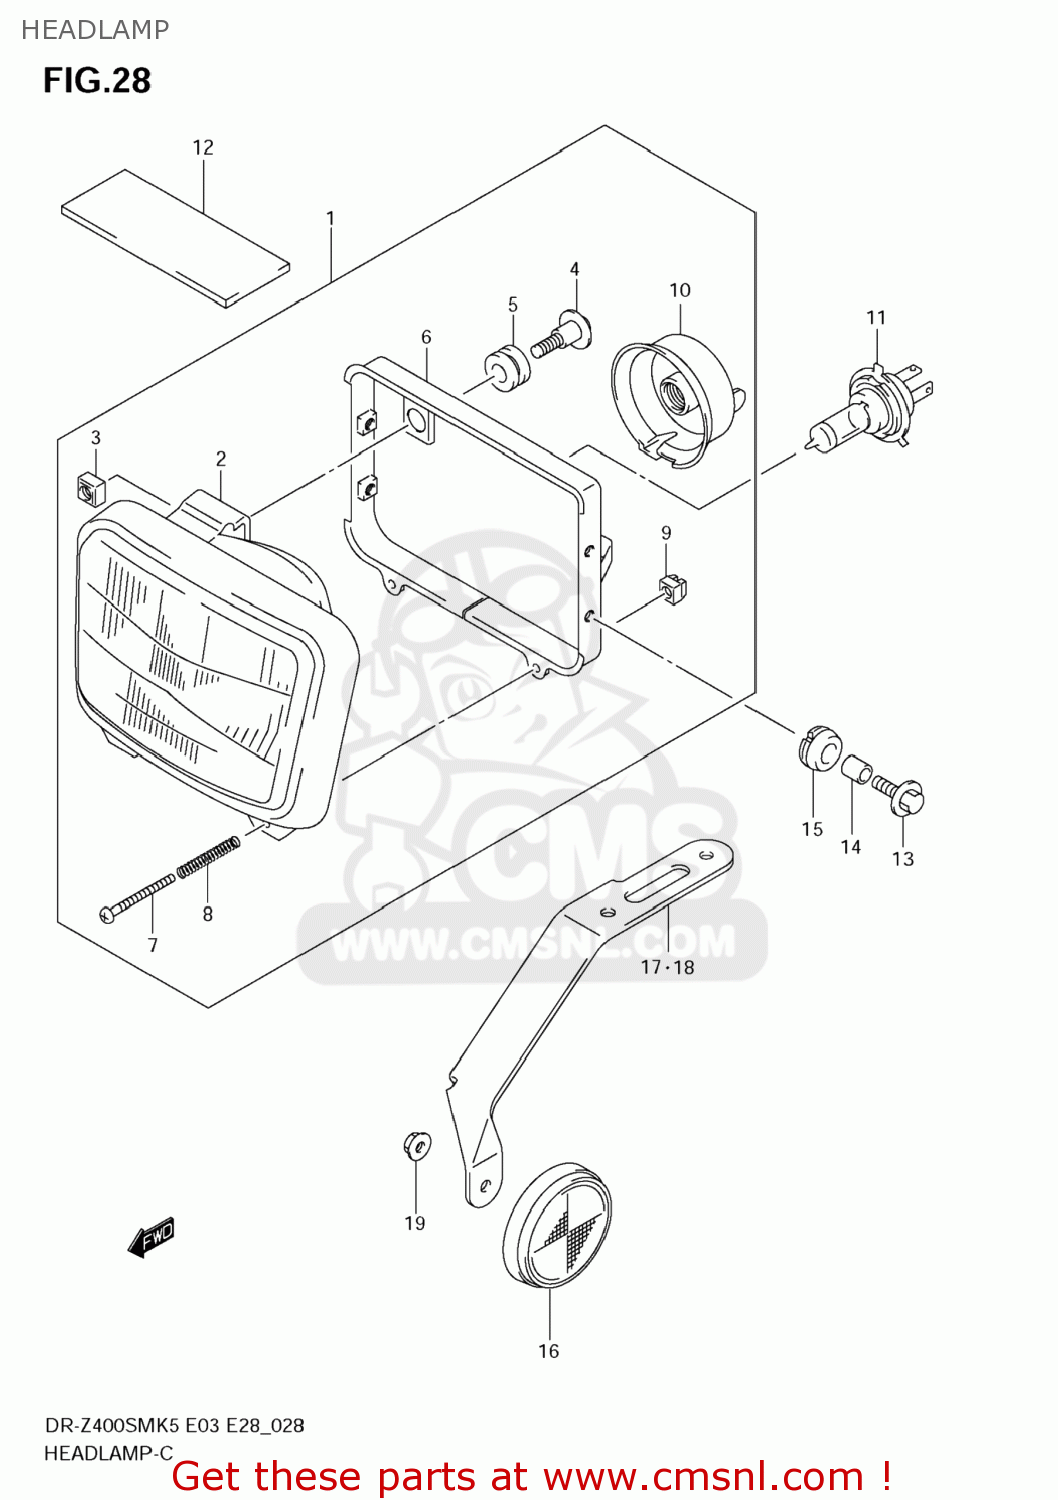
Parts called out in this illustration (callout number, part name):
1	HEADLAMP ASSY
2	UNIT ASSY
3	NUT
4	SCREW,MOUNTING
5	CUSHION
6	HOUSING
7	SCREW,ADJUSTING
8	SPRING,ADJUSTING
9	NUT,ADJUSTING
10	COVER,SOCKET
11	BULB(12V60/55W,H4)
12	PROTECTOR,WIRING HARNESS
13	BOLT(6X20)
14	SPACER(6.5X10X10)
15	CUSHION
16	REFLECTOR,REFLEX
17	BRACKET,FR SIDE RR,R
18	BRACKET,FR SIDE RR,L
19	NUT
